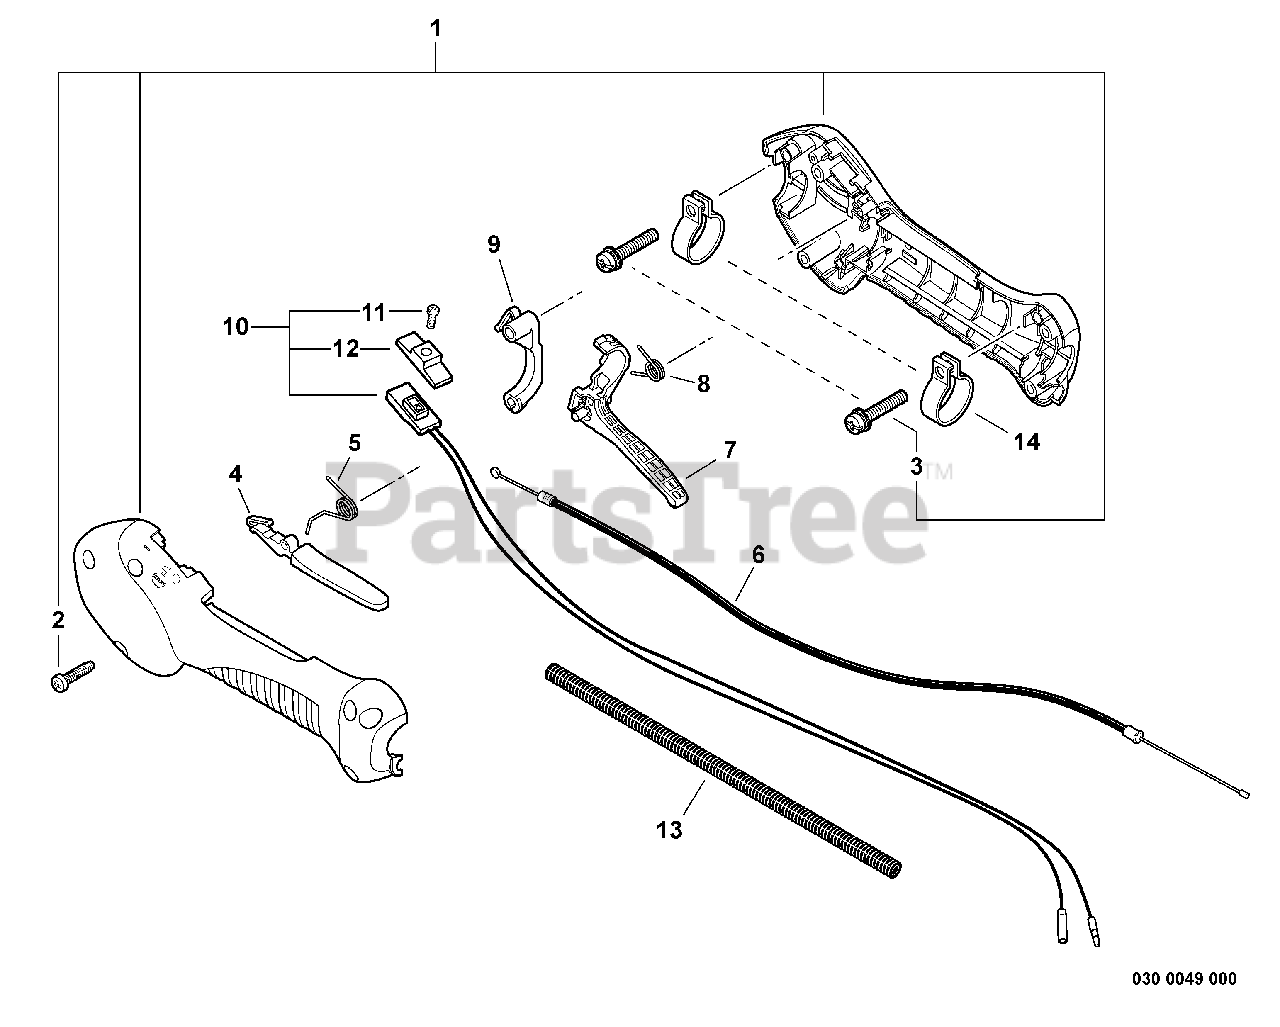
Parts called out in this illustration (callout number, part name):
1	CONTROL HANDLE ASSY
3	SCREW 5×20
4	LEVER, THROTTLE LOCKOUT
5	SPRING, TORSION
6	CABLE, THROTTLE
7	TRIGGER, THROTTLE
8	SPRING, TORSION
9	LOCKOUT, THROTTLE
10	SWITCH, ON-OFF
11	SCREW 3×10
12	KNOB, SWITCH - ORANGE
13	TUBE, FLEXIBLE
